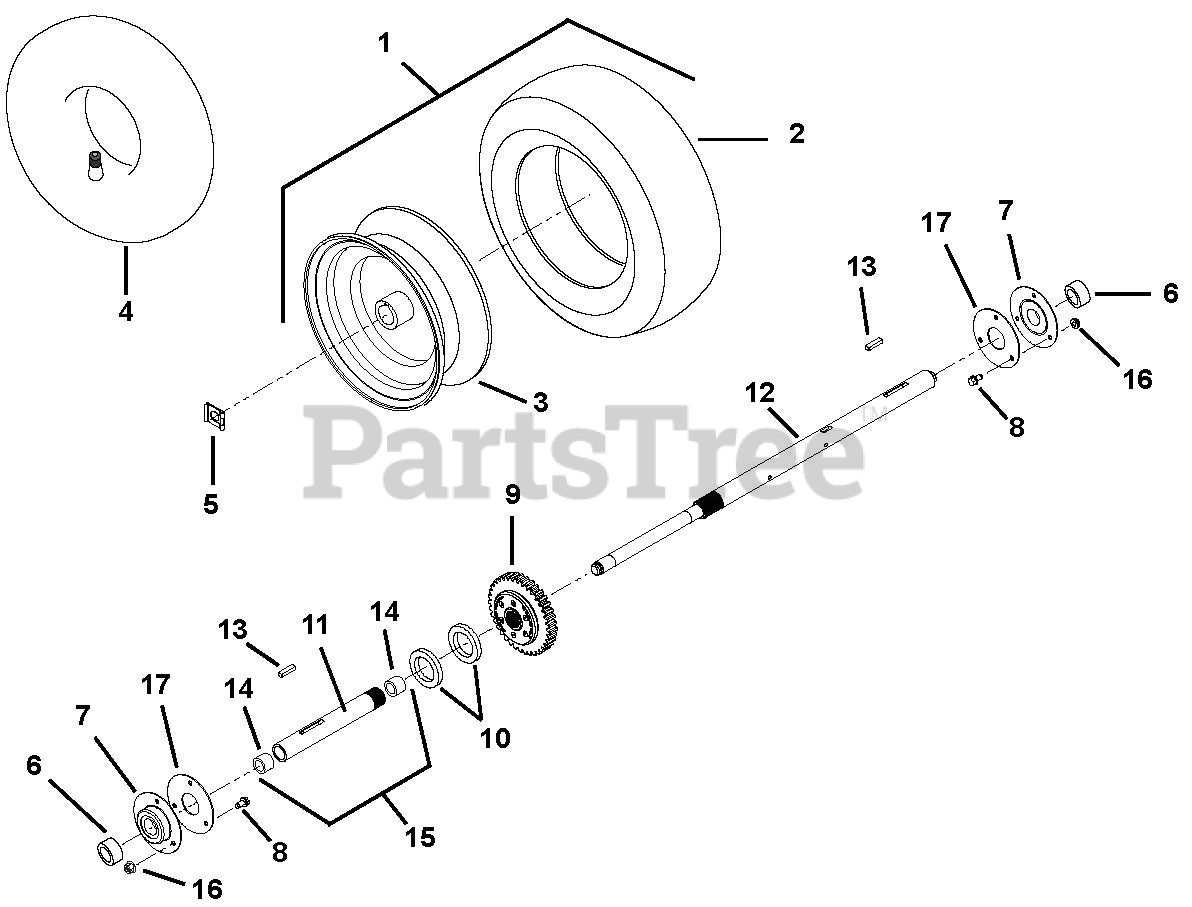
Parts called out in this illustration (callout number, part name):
1	TIRE/WHEEL,RH 16X4.8-8 DIFF T2
1	TIRE/WHEEL,LH 16X4.8-8 DIFF T2
1	TIRE/WHEEL, RH 16X6.50-8 DIFF
1	TIRE/WHEEL, LH 16X6.50-8 DIFF
2	TIRE, 4.80-8 K478
2	TIRE, 16X6.50-8 K478
3	HUB, WHEEL - 16X4.8-8 DIFF
3	HUB, WHEEL - 16X6.5-8 DIFF
4	TUBE
5	CLIP, SNAP .625 DIA
6	SPACER, PRO AXLE BEARING
7	BRG-FLG 1.003/1.000 3 BOLT
8	@BLT-HEX .25-20X.75 GR5 YWZC
9	DIFFERENTIAL, AUTOMATIC
10	WSHR-FL-STL- 1.062X2.0X.134 YZ
11	AXLE, SHORT-PRO AUTO DIFF
12	AXLE, LONG-PRO AUTO DIFF
13	KEY-RECT .25X.188X1.00
14	BSHG-SLV .706X.764X.75 BRZ
15	AXLE, SHORT-AUTO W/BUSHINGS
16	@NUT-LK-TOP-FLG .25-20 YWZC
17	PLATE, BEARING SPACER
